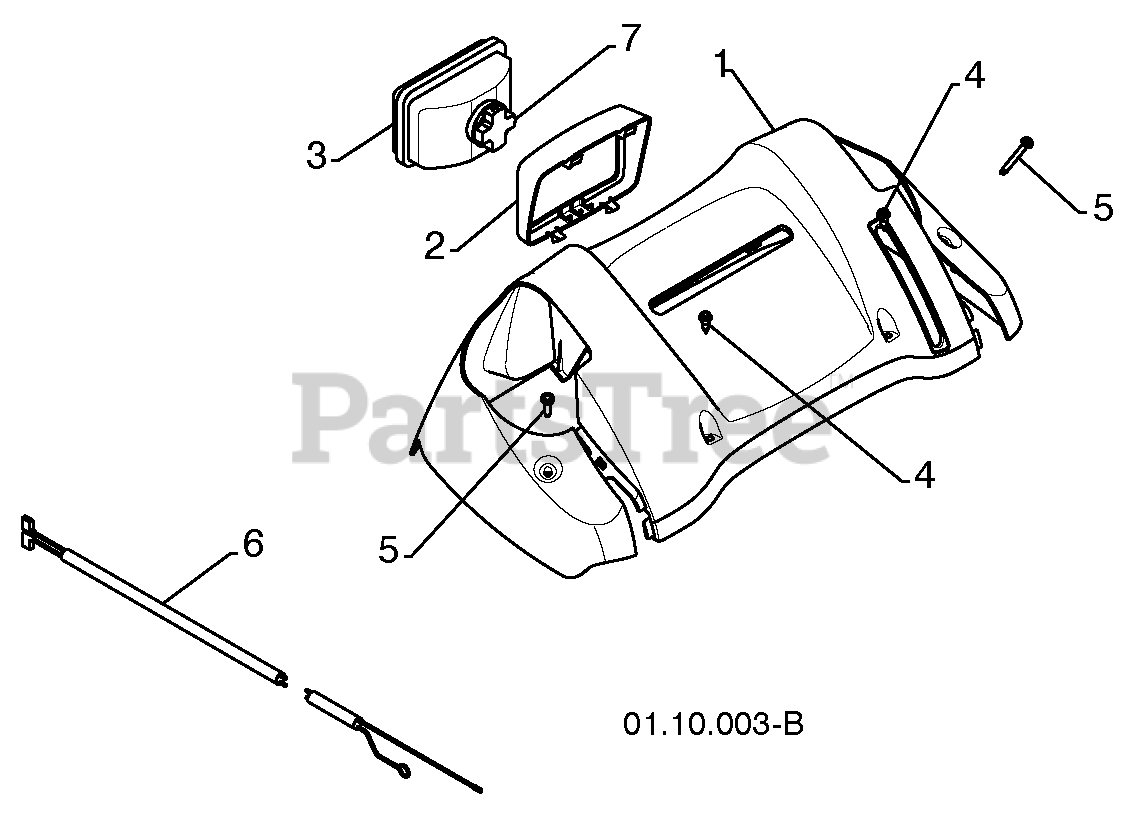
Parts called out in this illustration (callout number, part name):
1	CONSOLE PANEL
2	HEADLIGHT BEZEL
3	FLOOD HEADLIGHT
4	SHOULDER SCREW 10-24 X .625
5	SCREW 10-24 X 1.25
6	WIRE HARNESS
7	BULB
